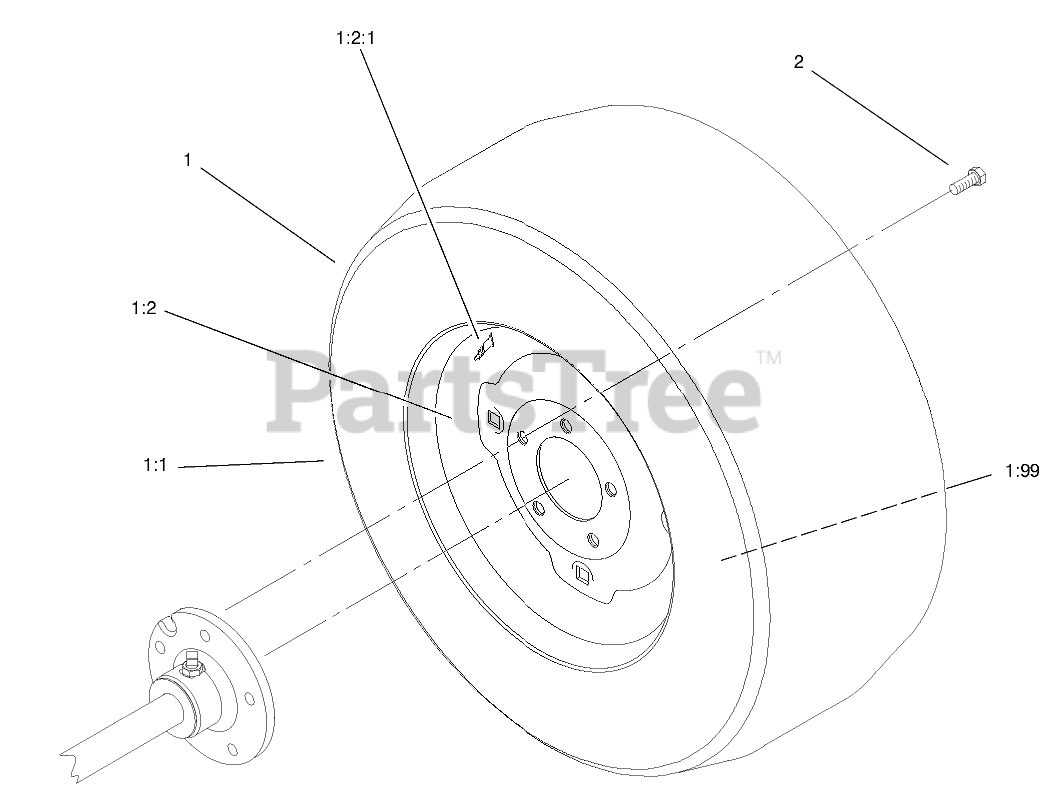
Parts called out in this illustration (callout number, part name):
1	Wheel & Tire ASM
1:2	RIM ASM
1:2:1	VALVE
1:99	TUBE-INNER
2	BOLT-LUG
